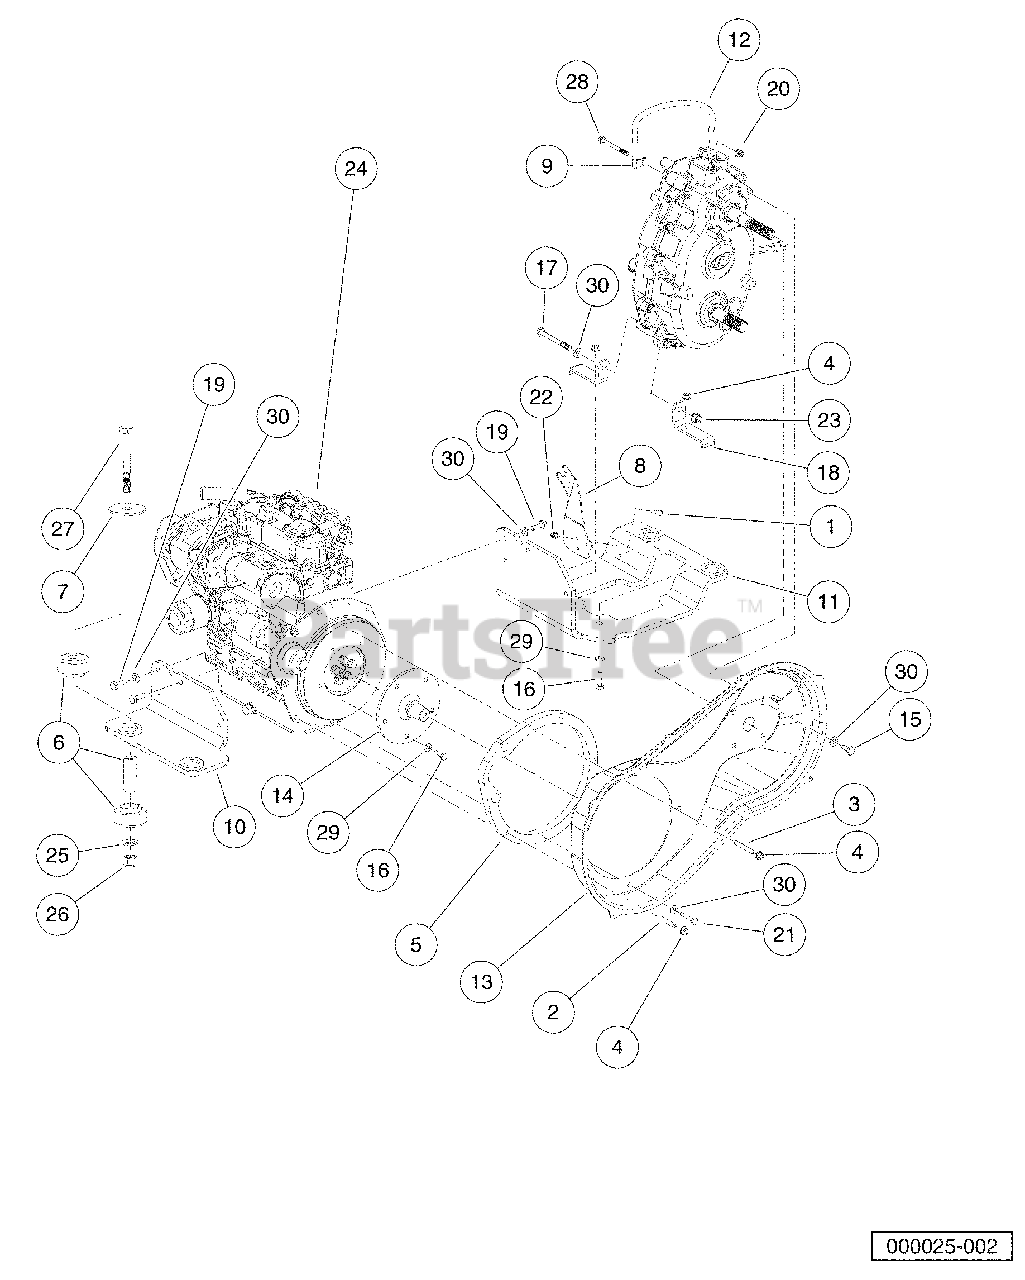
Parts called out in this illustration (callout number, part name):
1	Screw, M6-1.00 X 25mm Hex Cap
2	Stud, M8-1.25 X 50 mm Two-Ended
3	Stud, M8-1.25 X 60mm Two-Ended
4	Nut,m8,all Metal Lock
5	Spacer, Engine, Diesel
6	Isolator Ring and Bushing
7	Washer, Snubbing, Ring N Bush
8	Bracket, FNR Trans Cable
9	P-Clamp, Insulated .312 In
10	Plate, Engine Mounting, Weld, Left-Hand
11	Plate, Engine Mounting, Weld, Right-Hand
12	Hose, Vent, Transmission
13	Cover, CVT Inner, Diesel
14	Shaft, CVT Adapter
15	Bolt, M10 X 1.5 X 20 Loctite
16	Bolt, M8 X 1.25 X 25 Loctite
17	Bolt, M10 X 1.5 X 100 Loctite
18	Bracket, Transmission Mounting
19	Bolt, M10 X 1.25 X 25 Loctite
20	Lock Nut, Flg M8 X 1.25 Nylon
21	Bolt, M8 X 1.25 X 40 with Loctite
22	Nut Flg, M6 X 1.0 Nylon
23	Nut Flg M10 X 1.5 Nylon
24	Engine, Kubota, D722, with Closed Breather, 60a
25	Washer, M12 Hard
26	Locknut, M12x1.75 Nylon Insert.
27	Bolt, M12 X 1.75 X 90
28	Bolt, M8 X 1.25 X 80
29	Washer, M8 Hard
30	Washer, M10 Hard
